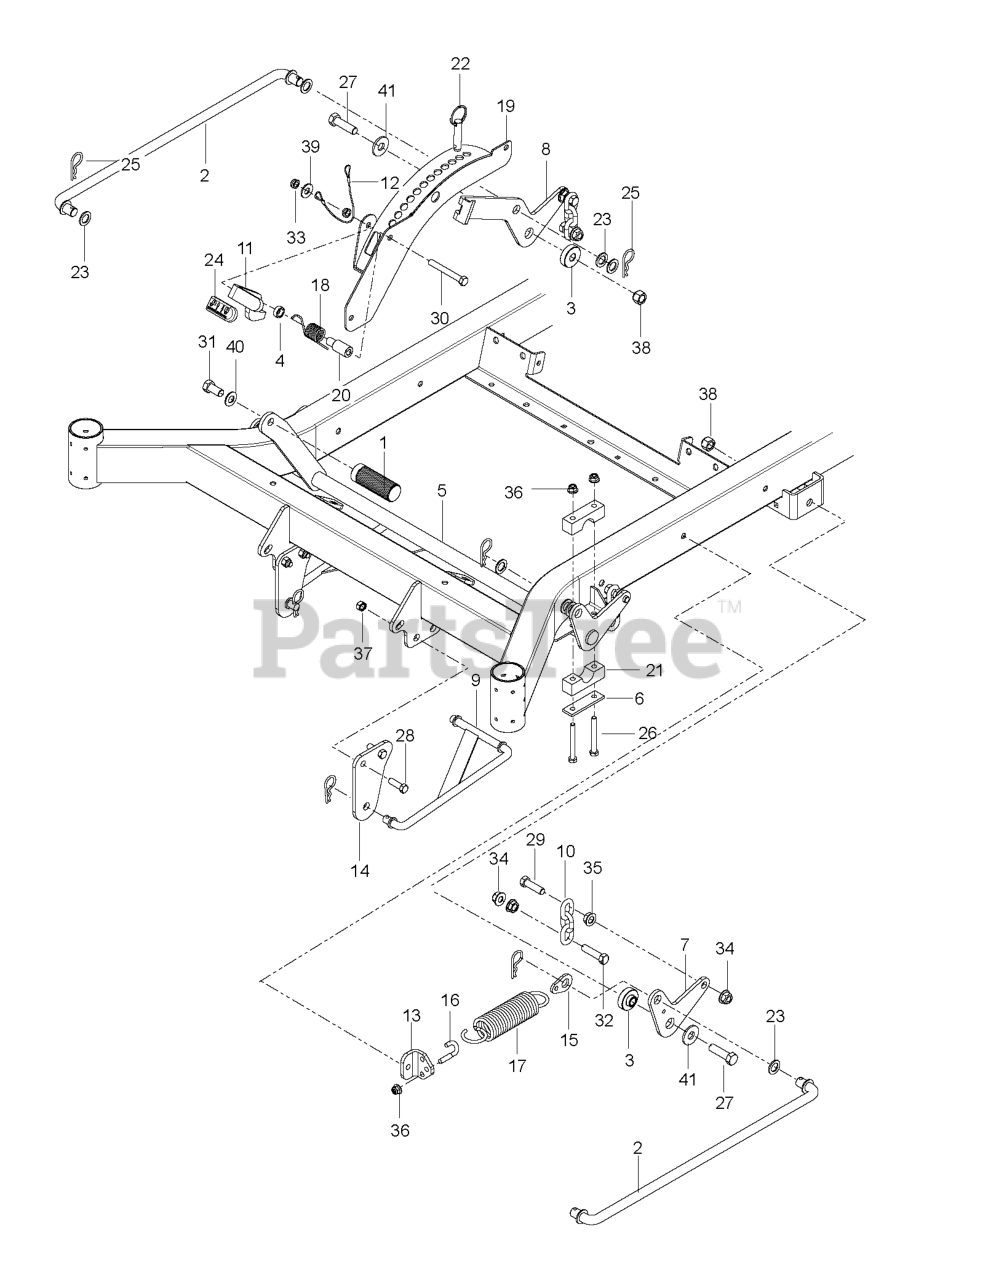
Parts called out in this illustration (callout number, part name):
1	PEDAL, DECK HEIGHT
2	CROSS LINK
3	SPACER.IDLER.METAL.POWDER
4	SPACER, .3
5	LIFT.PNT.MZ.DECK.WELD.E-DIP
6	REINFORCEMENT.PLATEX431
7	BELLCRANK, RR, LIFT
8	BELLCRANK, RR, RT
9	STRUT LINKAGE
10	LIFT CHAIN - 3 LINK
11	LATCH, TRANSPORT
13	MOUNT, SPRING
14	MOUNT, STRUT
15	TAB, SPRING
16	J-BOLT
18	SPRING, TORSION
19	HEIGHT, ADJUST, DECK
20	PIVOT, LATCH, TRANSPORT
21	PILLOW BLOCK
22	PIN, 1/2 X 1 1/2, DETENT RING
23	WASHER LT
24	GRIP, TRANSPORT-RELEASE
25	PIN, COTTER 1 3/4
26	BOLT HEX
27	HCS 1/2-13 X 1 3/4 GR 8
28	HCS 3/8-16X1.GRD.5.ZD
29	HCS 7/16C X 1 1/2
30	BOLT.HEX.FIN.3/8-16 X 3.GR5
31	HHCS 1/2-13 X 1
32	HCS 7/16 - 14 X 1 3/4
33	NUT HEX 3/8-16 NYLON, THIN
34	NUT 7/16-14 HEX WHIZ LK
35	NUT 7/16C WHIZ
36	5/16-18 NYLOC FLANGE NUT
37	NUT 3/8-16 NYLOC
38	NUT.LK.W/WSH.1/2.
39	WASHER 3/8 FLAT
40	WASHER, 7/16 DISC SPRING
41	WASHER.9/16 X 1 3/8 X 12 GA.
